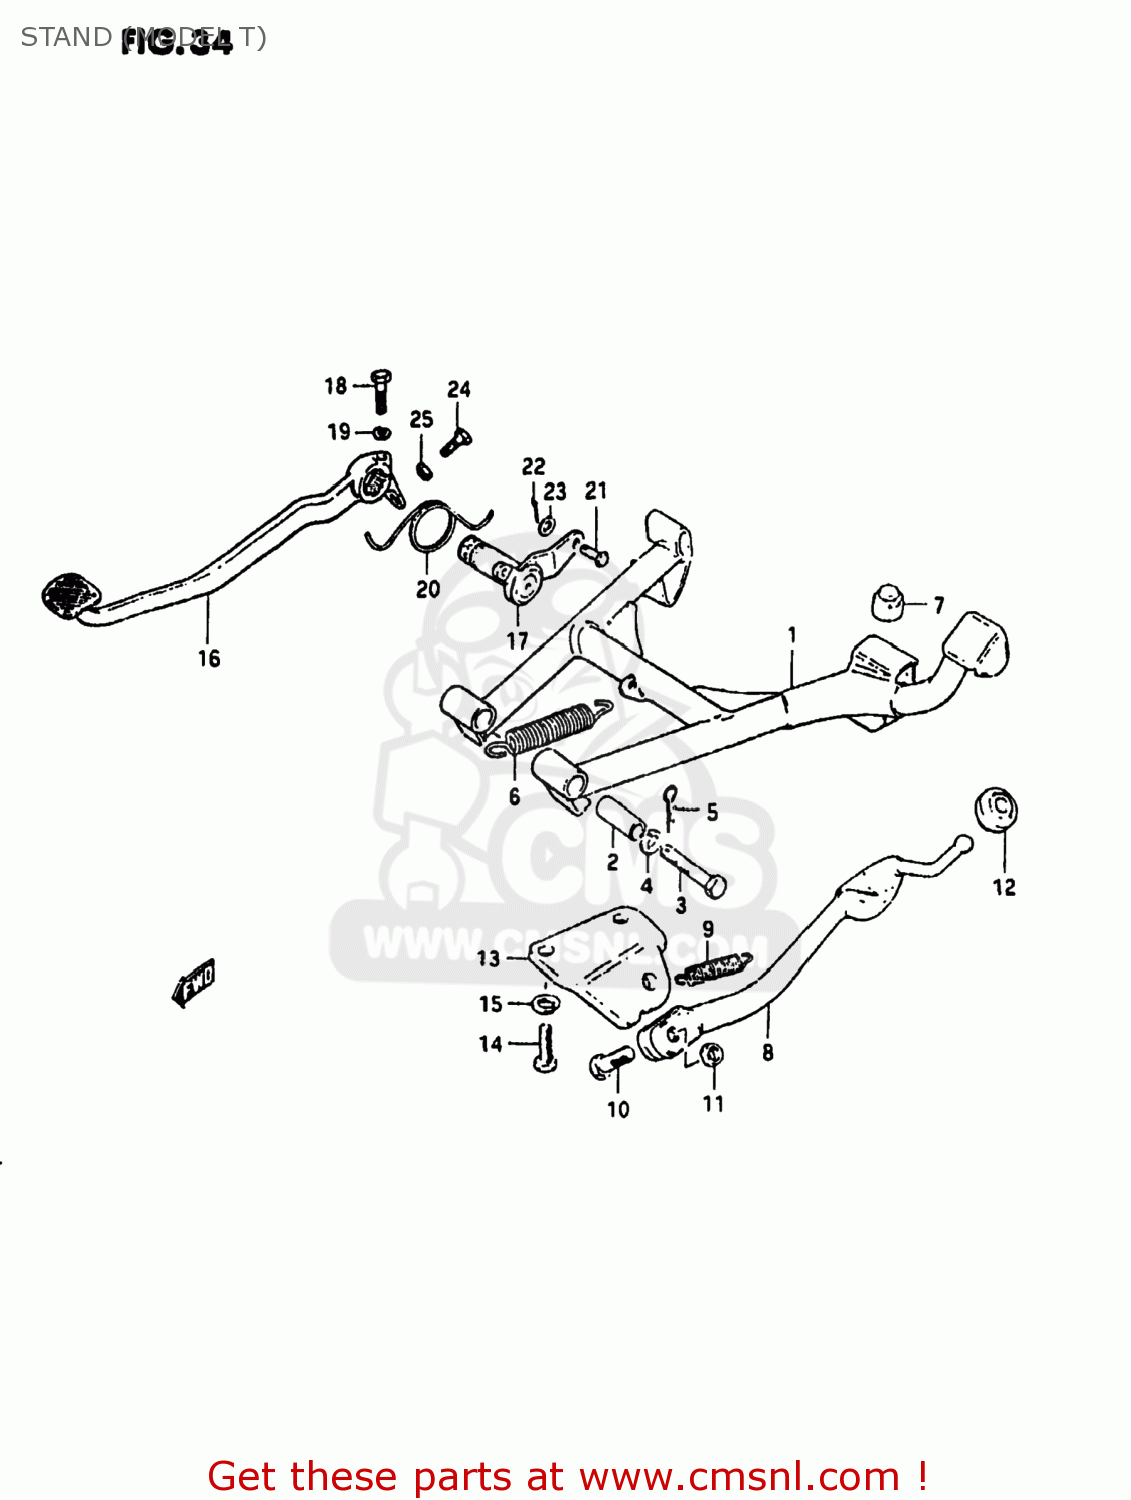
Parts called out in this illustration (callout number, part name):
1	STAND,CENTER
2	SPACER(10X16X38.8)
3	BOLT
4	LOCK WASHER
5	CLIP
6	SPRING
7	CUSHION
8	STAND,PROP
9	SPRING
10	BOLT(10X30)
11	NUT
12	CUSHION
13	BRACKET,SIDE STAND
14	BOLT
15	LOCK WASHER
16	PEDAL,BRAKE
17	ARM,BRAKE PEDAL
18	BOLT
19	LOCK WASHER
20	SPRING
21	PIN
22	PIN
23	WASHER
24	BOLT
25	NUT
